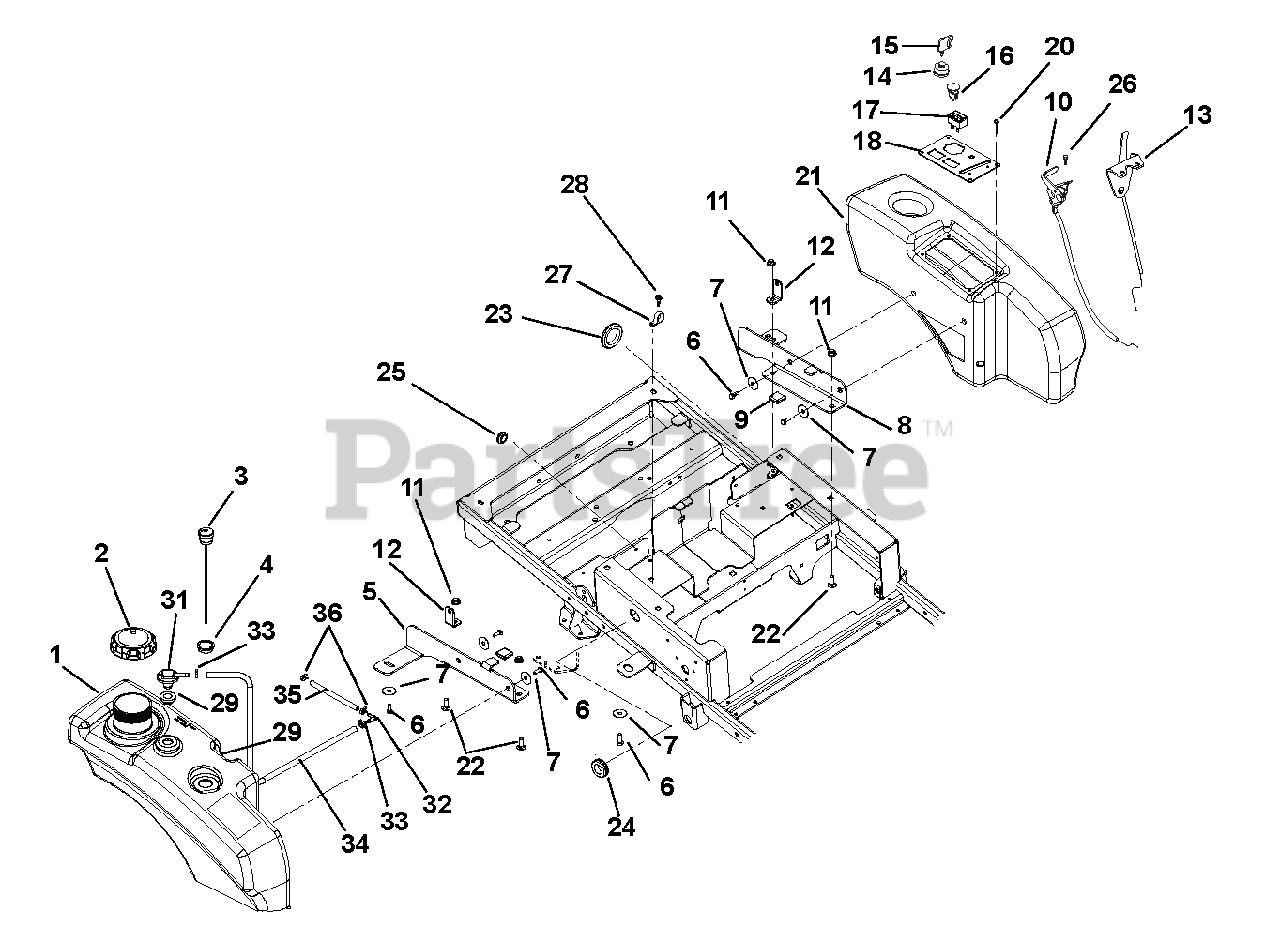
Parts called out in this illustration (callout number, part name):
1	TANK, XL NON-PERMEABLE FUEL
2	CAP, FUEL VENTIN AUTOLOCK
3	GAUGE, REMOTE FUEL 10.0"
4	GROMMET, FUEL GAGE
5	BRKT, RH REAR TANK MOUNT
6	BLT-SERHFWH .312-18X.50 YWZC
7	WSHR-FL-STL .347X1.254X.048YWZ
8	BRKT, LH REAR TANK MOUNT
9	GRIP, RUBBER (1.0X1.0X.187)BLK
10	CABLE, XL THROTTLE
11	@NUT-LK-NYL-FLG .38-16 YWZC
12	BRKT, HOOD PIVOT
13	CABLE, XL CHOKE
14	KEY SWITCH
15	KEY -W/CAP
16	SWITCH, CLUTCH
17	HOUR METER - DIGITAL
18	CONTROL PANEL
19	RIVET, PLASTIC .195 DIA.
20	SCR-HEX .25X14-.75
21	FENDER, XL
22	@BLT-RDHDSQNK .38-16X1.00 G5YZ
23	GROMMET 1.70ID X 2.0OD
24	GROMMET 1.0ID X 1.38 OD
25	GROMMET,RUBBER 5/8 ID/1.13 OD
26	@SCR-TAP 10-24X.50 HWH TR YWZC
27	CLAMP, CUSHIONED STEEL .75
28	@SCR-TAP .38-16X.50 HWH TR YWZ
29	ASM, FUEL PICK-UP - XL
30	GROMMET, REMOTE VENT NITRILE
31	VENT, ROLL-OVER (.25"ID HOSE)
32	FITTING-3/16X1/4 90DEGREE VAC
33	CLAMP, FUEL LINE
34	HOSE, .25 LOW-PERM BULK GAS
35	HOSE, .188 LOW-PERM BULK GAS
36	CLAMP-HOSE, SPRING .188
